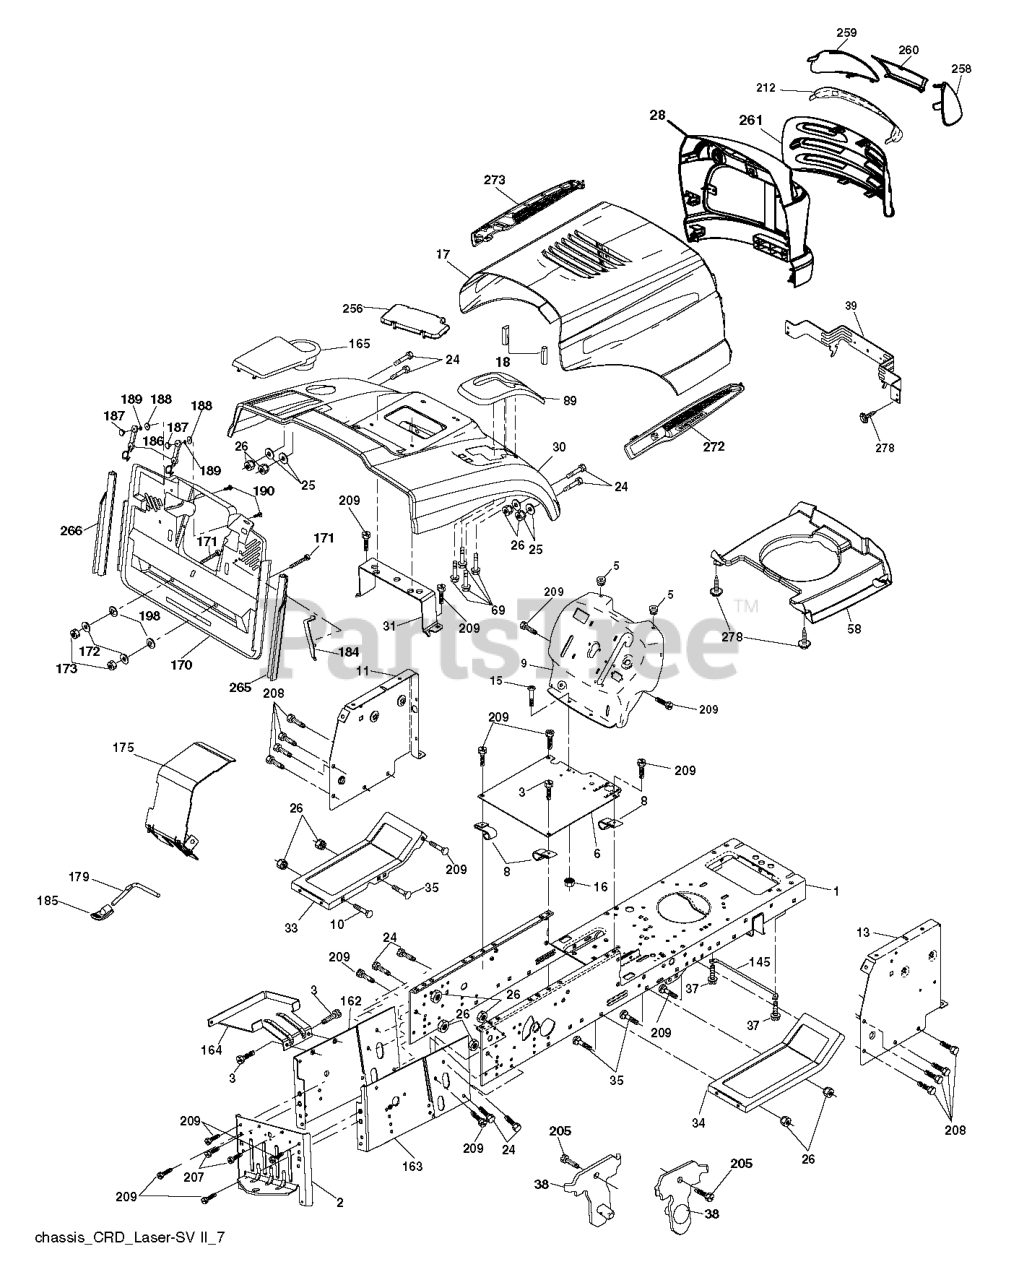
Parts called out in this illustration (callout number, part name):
2	DRAWBAR
3	SCREW 3/8-16X3/4
5	BUMPER.RUBBER.HOOD
6	PLATE
8	CLIP,INSULATOR
9	DASH.SLK.LT.PL.CC.NA.NHM.CE
10	BOLT D
11	PANEL.DASH.LH.LTX
13	PANEL ASM, DASH RH
15	Screw, Machine, Truss Head 5/16-18 UNC x 3/4
16	NUT
17	HOOD.PNT.LASER.SV.LT.668
18	BUMPER.HOOD.LARGE.1.75"
24	BOLT
25	WASHER
26	NUT
28	GRILLE.HUSQ.LASER.LT.668
30	FENDER.PNT.CRD.MS-668
31	BRACKET SUPPORT FENDER
33	FOOTREST.LH.BLACK
34	FOOTREST.RH.BLACK
35	BOLT
37	Screw 5/16-18 x 1/2 Hex, Self Tapping 5/16-18 x 1/2
38	BRACKET ASM PIVOT MOWER REAR
39	BRACKET PIVOT
69	SCREW.HI-LO.CONSOLE
89	CONSOLE.CRD.AUTO.BLACK.
145	ROD.PIVOT.HOOD
162	BRACKET
163	BRACKET EXTEN CHASSIS RH CRD
165	COVER.BATTERY.CRD.BLACK
171	BOLT
172	WASHER
175	DOOR TRAP
179	ROD PIVOT FBI
184	BRACKET.ACTUATOR.BAGGER.SRD
185	KNOB.BRAKE.PARKING.ROD
186	LATCH ASSY
187	WELDNUT
189	LOCKWASHER #10
190	SCREW
205	SCREW LT
207	SCREW, 5/16-18 X 1/2
208	SCREW 3/8-16X1/2
209	SCREW, 3/8-16X3/4
212	INSERT.LENS.REFLECTIVE
256	COVER FENDER CRD
258	LENS LH
259	LENS LH
260	COVER.LENS.HUSQ.LASER.LT.498
261	INSERT.GRILLE.HUSQLASER.LT.498
265	SEALING
266	SEALING
272	VENT.HOOD.LASER.III.SD.RH
278	SCREW.#10 X 0.750.BOS
